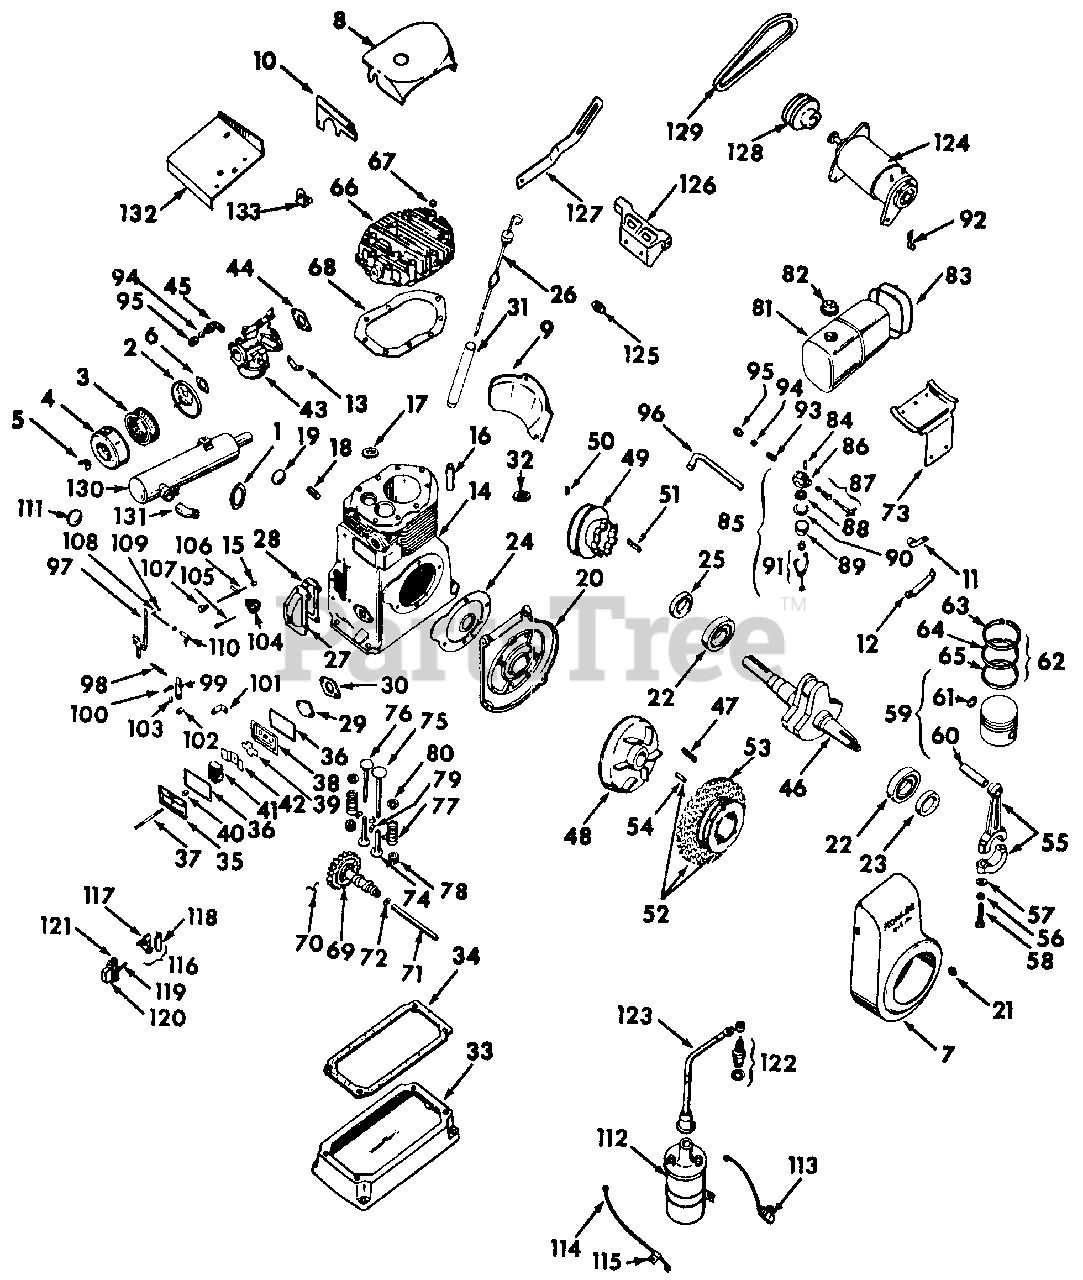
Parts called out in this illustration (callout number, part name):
1	Nut, Exhaust Muffler Elbow Lock
2	Base, Air Cleaner
3	Element, Air Cleaner Filter
4	Cover, Air Cleaner
5	Nut, Air Cleaner Wing
6	Gasket, Air Cleaner
7	Housing Assy, Blower
8	Baffle, Cylinder Head Air
9	Baffle, Cylinder Air
10	Baffle, Housing Side Air
11	Clip, Choke Cable
12	Bracket, Throttle Cable
13	Bracket, Choke
14	Crankcase Assy
15	Bearing, Needle
16	Guide, Valve
17	Insert, Exhaust Valve
18	Shaft, Governor
19	Plug, 1-1/8 Expansion, Crankcase
20	Plate, Crankcase Brg
21	Plug, 5/8 Button, Crankcase Bearing Plate
22	Bearing, Crankcase Ball
23	Seal, Crankcase Brg Plate Oil
24	Gasket, Brg Plate, .005
24	Gasket, Brg Plate, .010
25	Seal, Crankcase Oil
27	Cover, Camshaft
28	Gasket, Camshaft
29	Cover, Fuel Pump Pad
30	Gasket, Fuel Pump Pad Cover
31	Tube, Oil Fill
32	Insert, Intake Valve
33	Base, oil Pan
34	Gasket, Oil Pan Base
35	Cover, Breather
36	Gasket, Breather
37	Stud, Breather Cover
38	Plate, Breather
39	Reed, Breather
40	Seal, Breather
41	Filter, Breather
42	Baffle, Breather
43	Carburetor Assy
44	Gasket, Carburetor
45	Elbow, Carburetor to Fuel Line
47	Key, Crankshaft
49	Pulley w/Clutch Drive Plate, Flywheel
50	Screw, Flywheel Pulley Set
51	Key, 1/4 x 7/8 Sq Parallel
52	Cup Assy, Flywheel Drive
53	Screen, Drive Cup Grass
54	Pin, Flywheel Drive Cup
55	Rod Assy, Connecting, Std
55	Rod Assy, Connecting, .010 U/S
56	Washer, Connecting Rod Lock
57	Wahser, Connecting Rod
58	Screw, Connecting Rod
59	Piston Assy, Std
59	Piston Assy, .010 O/S
59	Piston Assy, .020 O/S
59	Piston Assy, .030 O/S
60	Pin, Piston, Std
60	Pin, Piston, .005 O/S
61	Retainer, Piston Pin
62	Ring Set, Piston, Std
62	Ring Set, Piston, .010
62	Ring Set, Piston, .020
62	Ring Set, Piston, .030
63	Ring, Compression
64	Ring, Center Compression
65	Ring, Oil Control
66	Head, Cylinder
67	Washer, Cylinder Head
68	Gasket, Cylinder Head
69	Camshaft Assy
70	Spring, Camshaft Actuating
71	Pin, Camshaft
72	Shim, Camshaft, .005
72	Shim, Camshaft, .010
73	Bracket, Fuel Tank
74	Tappet Assy, Valve
75	Valve, Intake
76	Valve, Exhaust
77	Spring, Vale
78	Retainer, Valve Spring
79	Key, Valve Spring Retainer
80	Retainer, Valve Spring upper
81	Tank Assy, Fuel w/Filler Cap
82	Cap, Fuel Filler
83	Strap, Fuel Tank
84	Nipple, 1/8 X 3/4 C-Z Pipe
85	Filter Assy, Fuel
86	Body, Fuel Filter
87	Valve Assy, Needle
88	Screen, Filter
89	Bowl, Fuel Filter Glass
90	Gasket, Fuel Filter Bowl
91	Bail Assy, Fuel Filter Bowl
92	Clip, Cable Harness
93	Connector, Fuel Filter
94	Sleeve, Fuel Line
95	Nut, Fuel Line
96	Line, Fuel Filter to Carburetor Fuel
97	Lever, Governor
98	Spring, Governor
99	Bracket, Speed Control
100	Clamp, Control Bracket
101	Bracket, Adjusting Screw
102	Spacer, Adjusting Screw
103	Washer, Adjusting Screw Spacer
104	Gear Assy, Governor
105	Pin, Governor Stop
106	Shaft Assy, Governor Cross
107	Bushing, Cross Shaft
108	Rod, Ball Joint Throttle
109	Retainer, Throttle Rod
110	Joint, 10-32 X 1/4 Ball
111	Plug, 1-1/8 Expansion
112	Coil, Ignition
113	Condenser, ignition Coil
114	Cable Assy, Condenser to Breaker
115	Clip, Condenser to Breaker Cable
116	Bracket & Breaker Assy
117	Breaker Point Set
118	Bracket, Point Breaker
119	Rod, Breaker
120	Cover, Breaker
121	Gasket, Breaker Cover
122	Plug, Spark
123	Kit, Hi-Tension Spark Plug Cable Lead
124	Motor Generator
125	Shim, Motor Generator Mounting Bolt
126	Bracket, Motor Generator Mounting
127	Brace, Motor Generator Adjusting
128	Pulley, Motor Generator Drive
129	Belt, Motor Generator Drive
130	Muffler, Exhaust
131	Tube, Exhaust Muffler
132	Baffle, Heat
133	Angle, Hanging Strap
